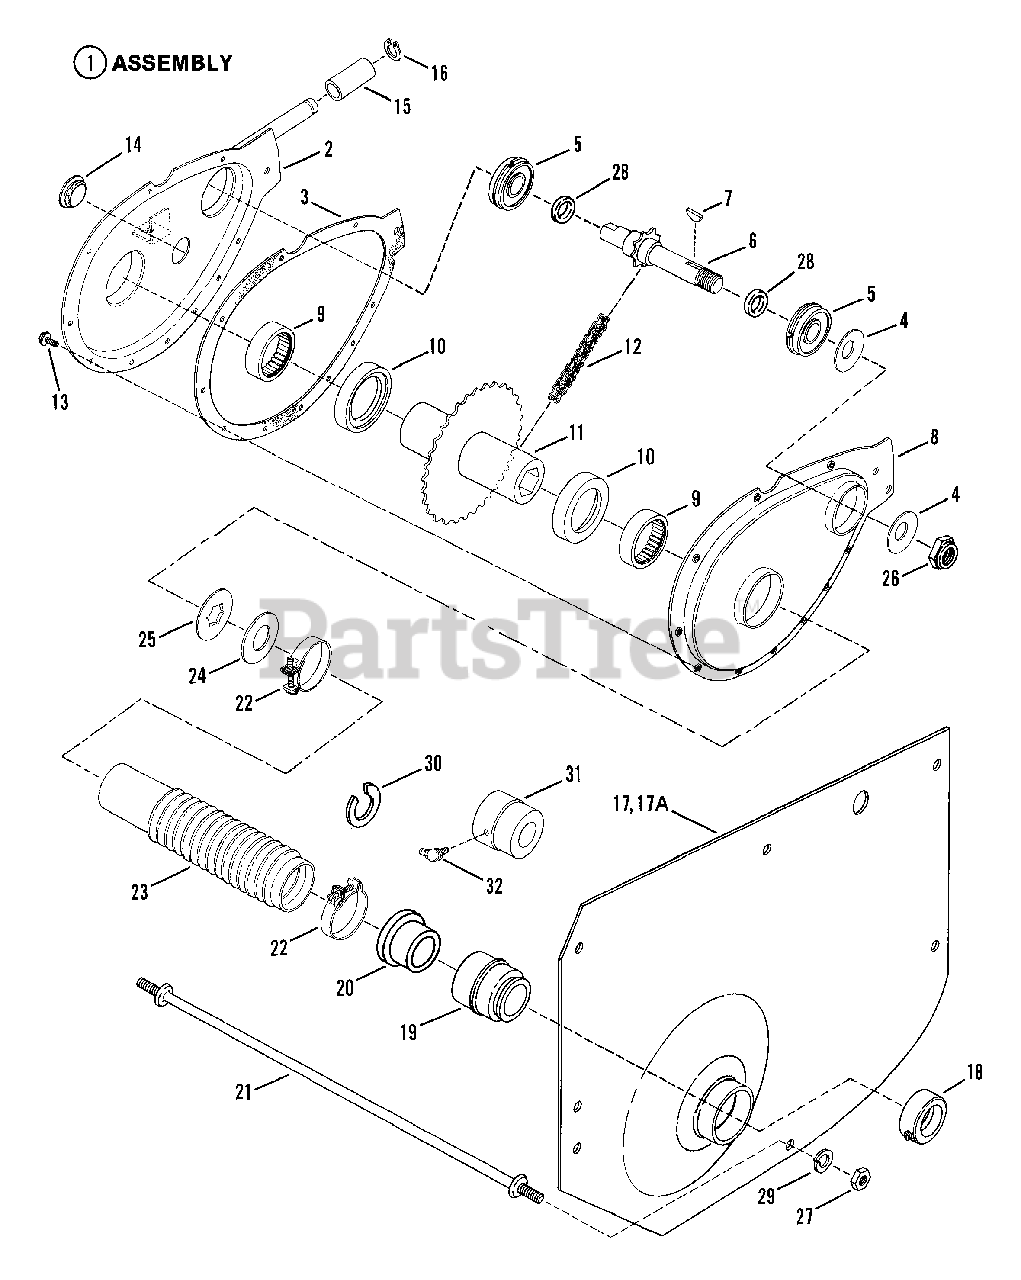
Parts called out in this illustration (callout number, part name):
1	ASSEMBLY, Chain Case
2	CASE, Sprocket
3	GASKET, Case-Cover
4	WASHER, Belleville
5	BEARING, Ball
6	SPROCKET & SHAFT
7	KEY, Woodruff
8	COVER, Chain Case
9	BEARING, Needle
10	WASHER, Nylon Thrust
11	HUB & SPROCKET
12	CHAIN
13	SCREW, #10-24 x 1/2" Hex Washer Self-Tap (Torx)
14	PLUG, Oil Fill & Check
15	ROLLER
16	RING, Retaining
17	FENDER, Left Hand 1.628" ID Hole (12 & 14 HP Models)
17A	FENDER, Left Hand 1.744" ID Hole (6.5 & 8 HP Models)
18	COLLAR, Lock
19	BEARING, Left Hand Fender (12 & 14 HP Models)
20	SPACER, Left Hand (12 & 14 HP Models)
21	ROD, Cross-Tie
22	CLAMP, Boot
23	BOOT, Oil Seal
24	WASHER, Thrust Nylon
25	WASHER, Thrust
26	NUT, 5/8-18 Hex, E. E.S.
27	NUT, 5/16-24 Hex
28	"O" - RING
29	WASHER, 5/16 Split Lock
30	WASHER, Shim
31	BEARING, Left Hand Fender (6.5 & 8HP Models)
32	FITTING, Lube (6.5 & 8 HP Models)
